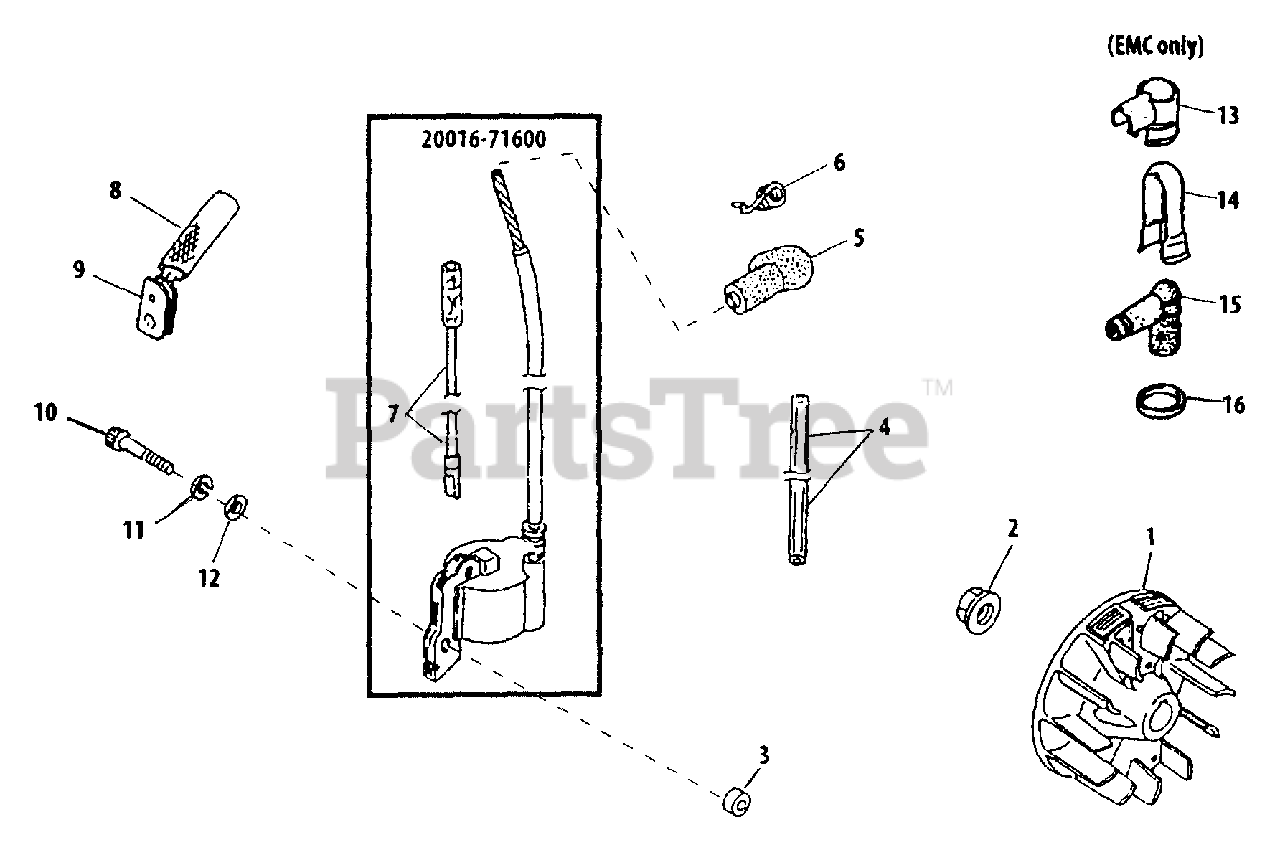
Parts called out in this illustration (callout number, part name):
1	FLYWHEEL
2	NUT M8
3	INSULATOR 4.2×11×6
4	TUBE, INSULATOR
5	CAP, SPARK PLUG
6	TERMINAL, SPARK PLUG
7	WIRE
8	TUBE, IGNITION COIL
9	GROMMET
10	BOLT
11	WASHER, SPRING 4 MM
12	WASHER 4 MM
13	COVER, CAP
14	SHIELD
15	CAP, SPARK PLUG
16	SEAL, SPARK PLUG
20016-71600	IGNITION COIL ASSY
